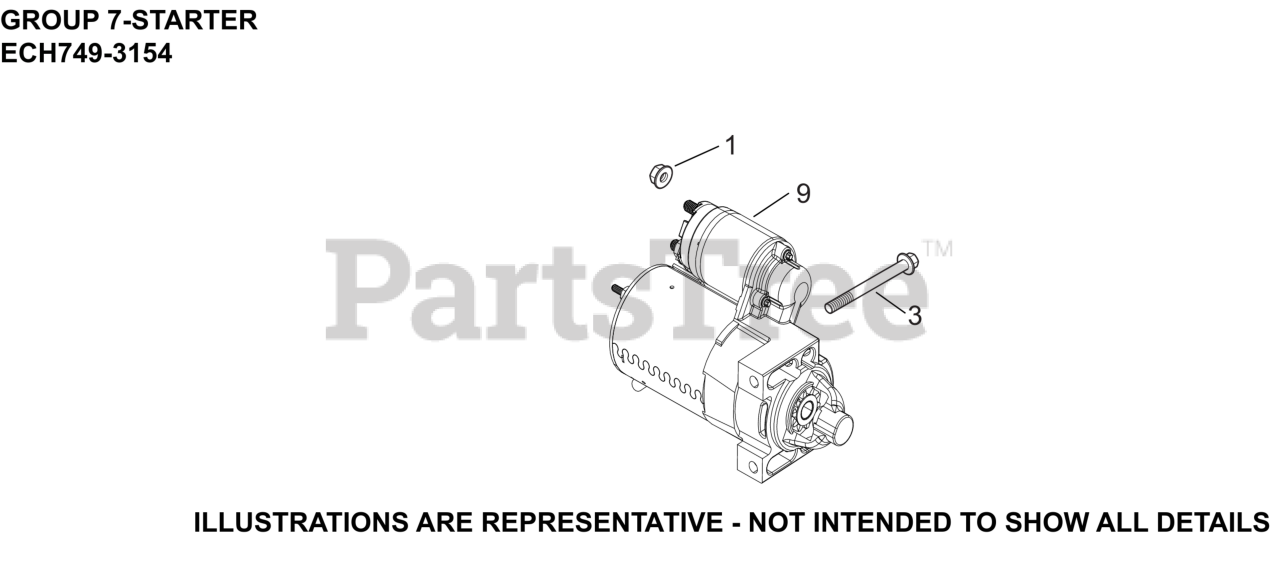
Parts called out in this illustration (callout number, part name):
1	NUT, FLG M8X1.25
3	SCREW, FLG M8X1.25X80
9	STARTER, SOLENOID SHIFT (25 098 09-S)
